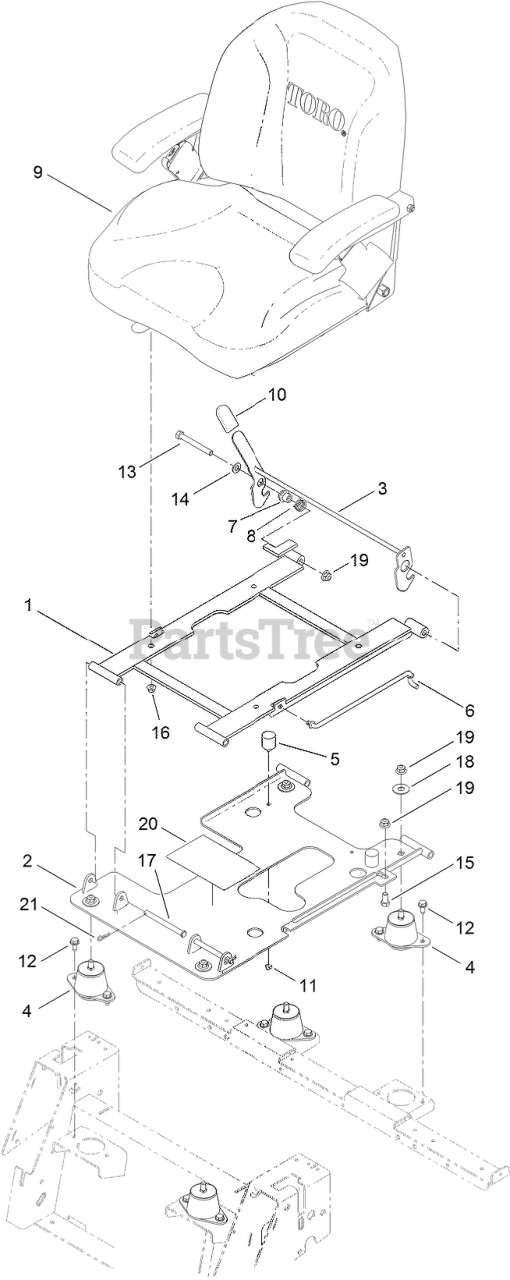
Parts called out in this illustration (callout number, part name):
1	SEAT PAN ASM
2	SEAT BASE ASM
3	LATCH ASM
4	ISOLATOR-SEAT
5	Bumper
6	ROD-PROP
7	BUSHING-LATCH, SEAT
8	SPRING-TORSION
9	SEAT ASM
10	GRIP-LEVER
11	NUT-LOCK, NI
12	SCREW-HWHTF
13	SCREW-HH
14	WASHER-FLAT
15	SCREW-HH
16	NUT-HF, NI
17	PIN-CLEVIS
18	WASHER-FLAT
19	NUT-HF, NI
20	DECAL-MAINTENANCE
21	PIN-COTTER
